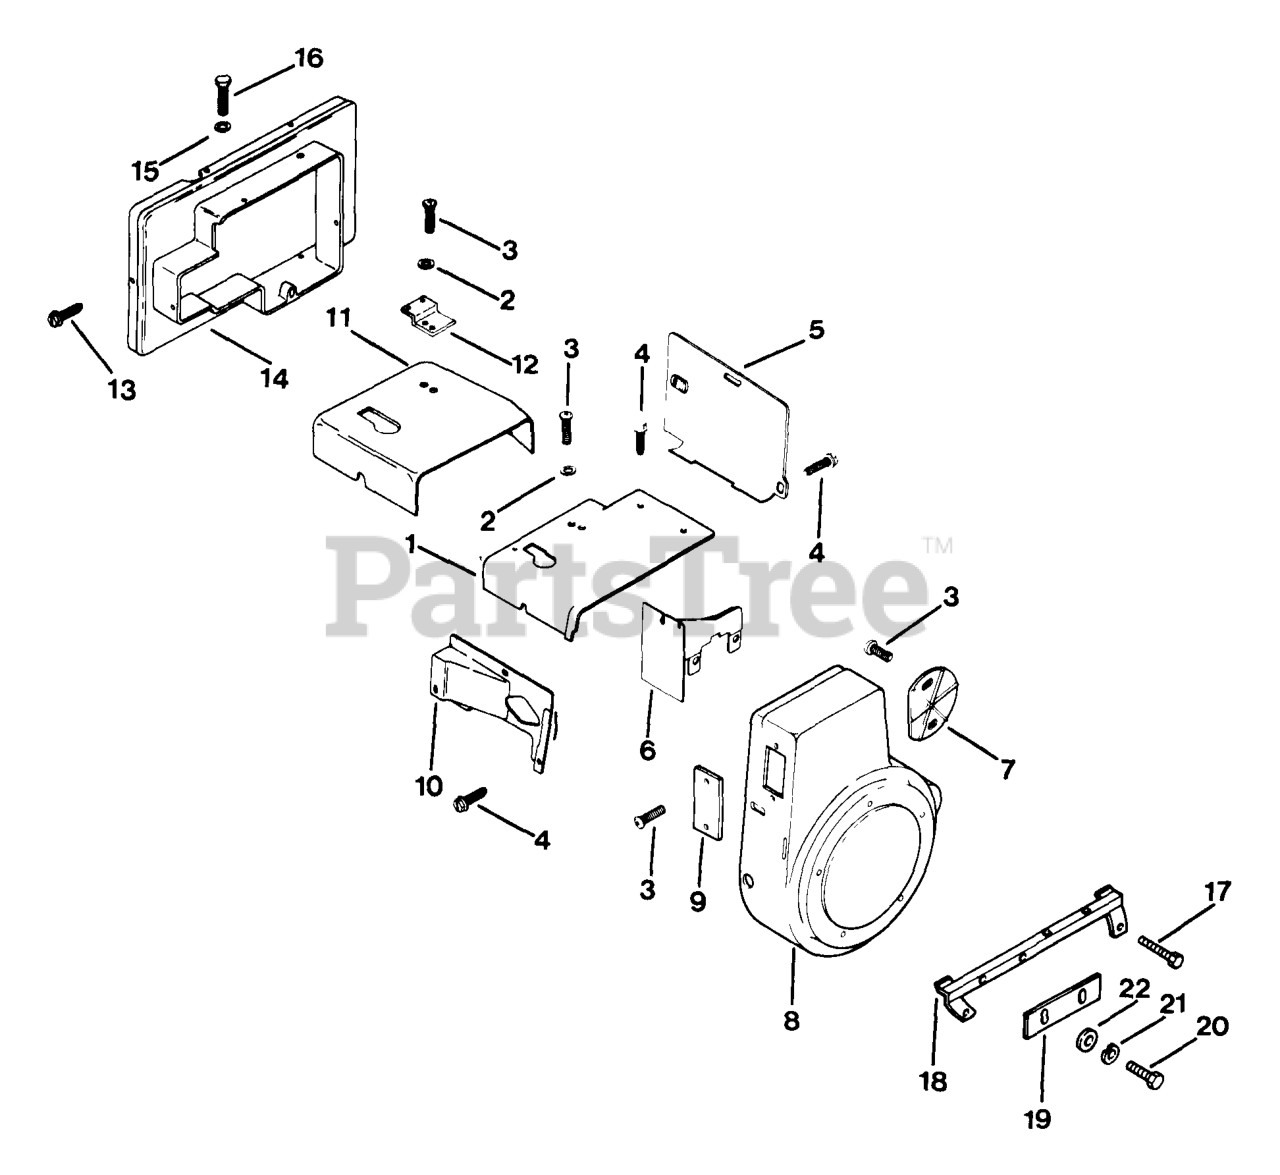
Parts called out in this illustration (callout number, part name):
2	WASHER, FLAT 1/4" (O.D. 5/8")
3	SCREW, POZ TRS HD 1/4-20X5/8" - DISCONTINUED
4	SCREW, WSH HD TAP 1/4-20-5/8" - DISCONTINUED
5	BAFFLE, CYLINDER
6	BAFFLE, INNER - DISCONTINUED
8	KIT, BLOWER HOUSING - DISCONTINUED
10	BAFFLE, SIDE AIR - DISCONTINUED
